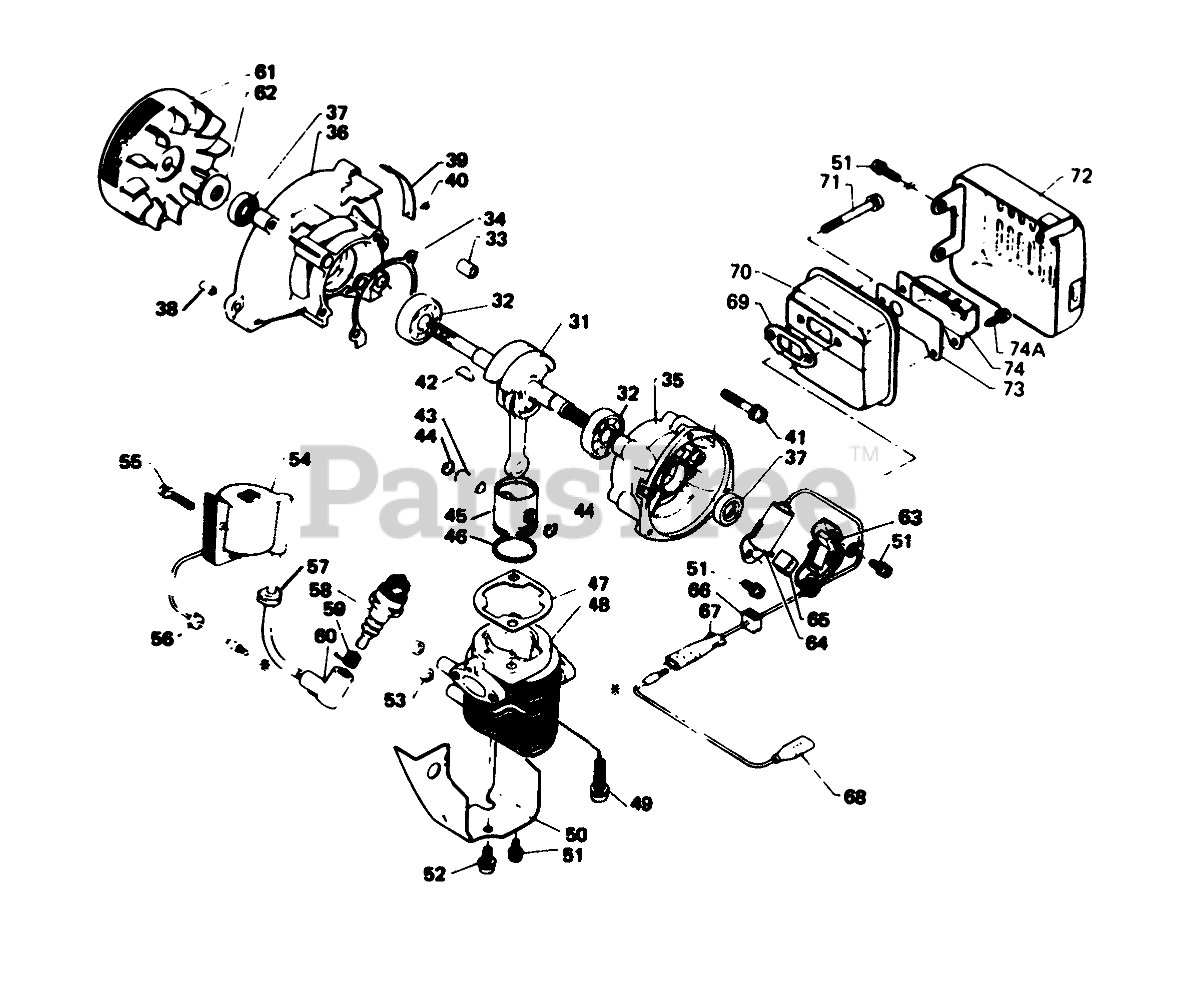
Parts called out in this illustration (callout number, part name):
31	Crank Shaft Assy.
32	Bearing
33	Knock Pin
34	Gasket, Crankcase
35	Crankcase Set
36	Crankcase Set
37	Oil Seal
38	Knockpin
39	Model Plate
40	Rivet
41	SCREW
42	Woodruff Key
43	Piston Pin
44	Circlip, Piston Pin
45	Piston
46	PISTON RING
47	Gasket, Cylinder Base
48	Cylinder
49	Screw
50	Cylinder Cover
51	SCREW
52	SCREW
53	Spacer
54	Ignition Coil
55	Screw
56	Grommet
57	Grommet
58	Spark Plug
59	Coil Spring-Plug Cap
60	Cap-Spark Plug
61	Flywheel
62	Spacer
63	POINT SET
64	CONDENSER
65	Oiler
66	Grommet
67	Primary Cord
68	Ground Lead
69	Gasket, Muffler
70	Muffler
71	Screw
72	Muffler Cover
73	Silencer
74	Deflector, Exhaust
74A	Screw
